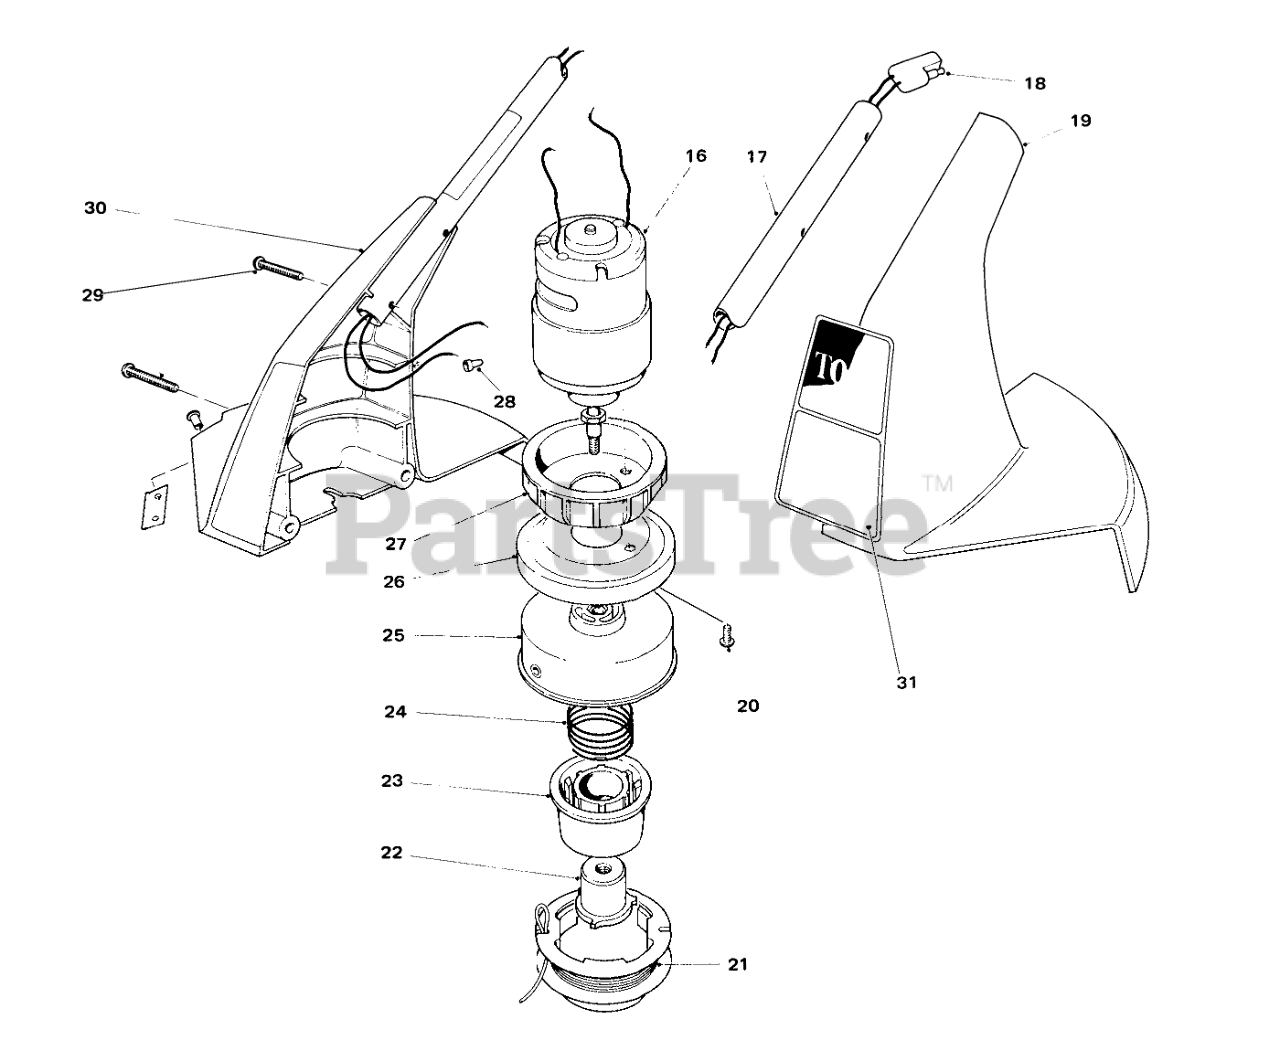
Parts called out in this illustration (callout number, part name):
16	Motor
17	EXTENSION HANDLE
18	WIRING HARNESS LOWER
19	Housing-L.H.
20	SCREW-PPH
21	Prewound Spool
22	DRIVER
23	CORE - SPOOL
24	Spring
25	Drum w/Eyelet
26	DRUM CUP
27	Casting-Heat Sink
28	CONNECTOR WIRE JOINT
29	SCREW-PLASTITE
30	R.H. Motor Housing (Incl. Ref. #17&18)
31	Decal-CL-700
